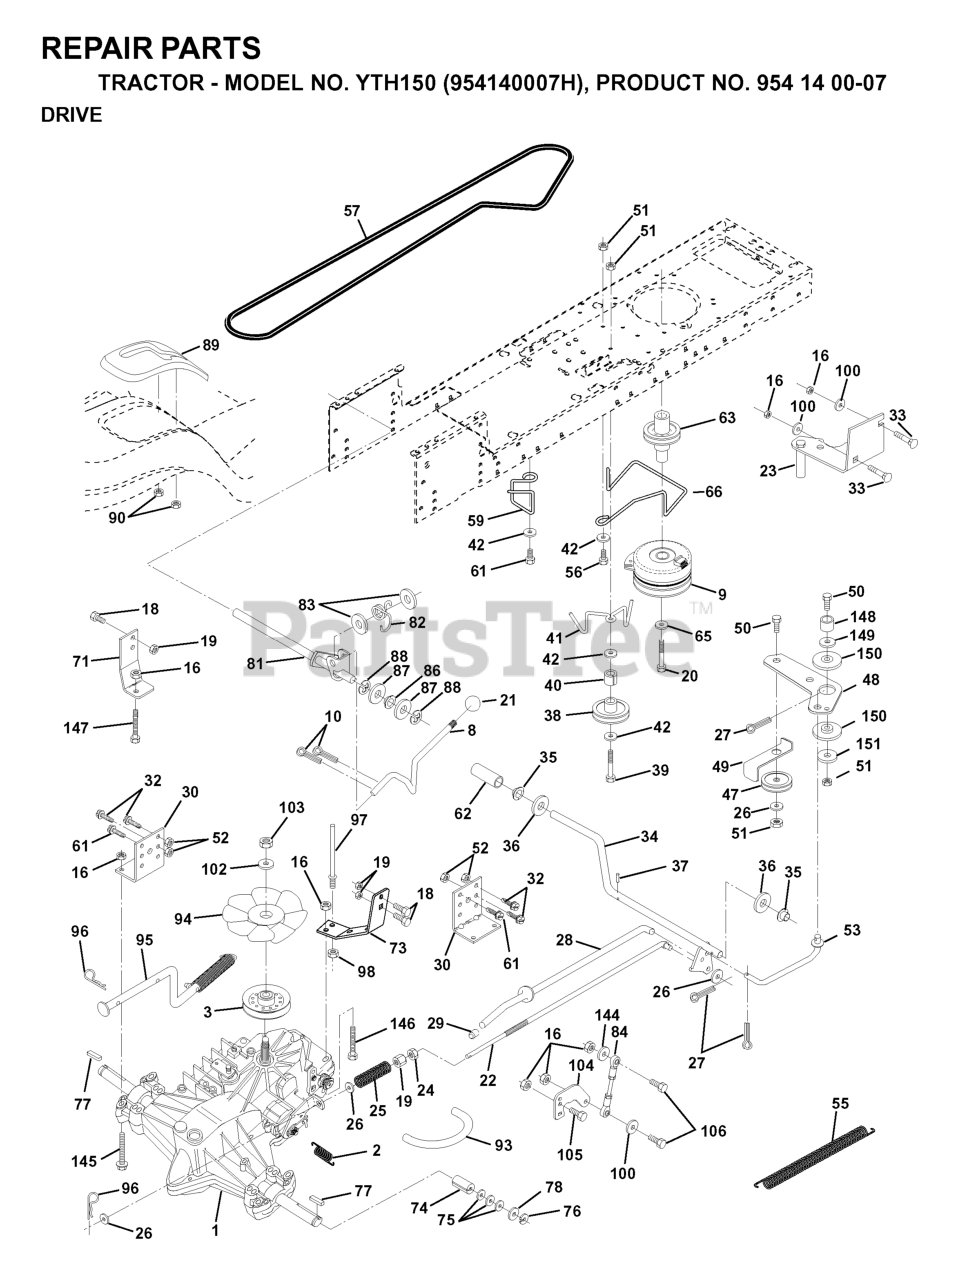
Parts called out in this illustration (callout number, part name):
1	TRANSAXLE ASSEMBLY
2	SPRING BRAKE
3	PULLEY, TRANSAXLE
8	ROD SHIFT FENDER
9	CLUTCH.ELECT.EVX.
10	PIN COTTER
16	NUT.71038.31-18.HEX.NYLOCK
19	NUT
20	BOLT HEX
21	KNOB.DELUXE.(PISTOL.GRIP).BLAC
22	ROD BRAKE HYDRO
23	BRACKET, ASM CLUTCH MTG
24	NUT
25	SPRING ROD LT
26	WASHER
27	COTTER PIN
28	ROD BRAKE PARK LT
29	PLUNGER CAP
30	BRACKET TRANSAXLE
32	BOLT
33	RP BOLT 5/16-18 X3/4 ZN/YEL GR
34	SHAFT, FOOT PEDAL
35	BEARING.NYLON
37	DRIVE PIN
38	FLAT IDLER PULLEY
41	KEEPER.BELT.IDLER.FLAT
42	WASHER
47	IDLER PULLEY
48	BELLCRANK, CLUTCH
49	RETAIN BELT
50	BOLT
52	LOCKNUT
53	LINK, CLUTCH LT
55	SPRING, RETURN LT
57	DRIVE BELT, LTH & YTH TRACTORS
59	KEEPER CENTER SPAN
61	SCREW
62	COVER, PEDAL (1 2)
63	PULLEY, CLUTCH ELECT EVX
65	LOCKWASHER
66	KEEPER BELT ENGINE
71	STRAP LH TORQUE
73	STRAP TORQUE RH HYDRO
74	SPACER SPLIT
77	SQUARE KEY
81	SHAFT ASSY
82	SPRING,TORSION
83	WASHER
89	SHIFT CONSOLE
90	NUT.PUSH.3/16
93	LINE FUEL HYD 4"
94	FAN 7" HYDRO
95	CONTROL ARM, BYPASS HYDRO
96	RETAINER M
97	KEEPER BELT RH
100	WASHER M
103	NUT.HEX.1/2-20
104	CONTROL ARM
106	BOLT.5/16-18X1-1/4 FULL.THREAD
144	Washer 11/32 x 5/8 x 16 Ga SD
146	Bolt Hex Flanged 5/16-18 Unc x 2
147	Bolt Hex Flanged 5/16-18 Unc x 2
149	SPACER RETAINER
150	BUSHING NYLON COLLERED
151	WASHER 12/32X2X10GA
